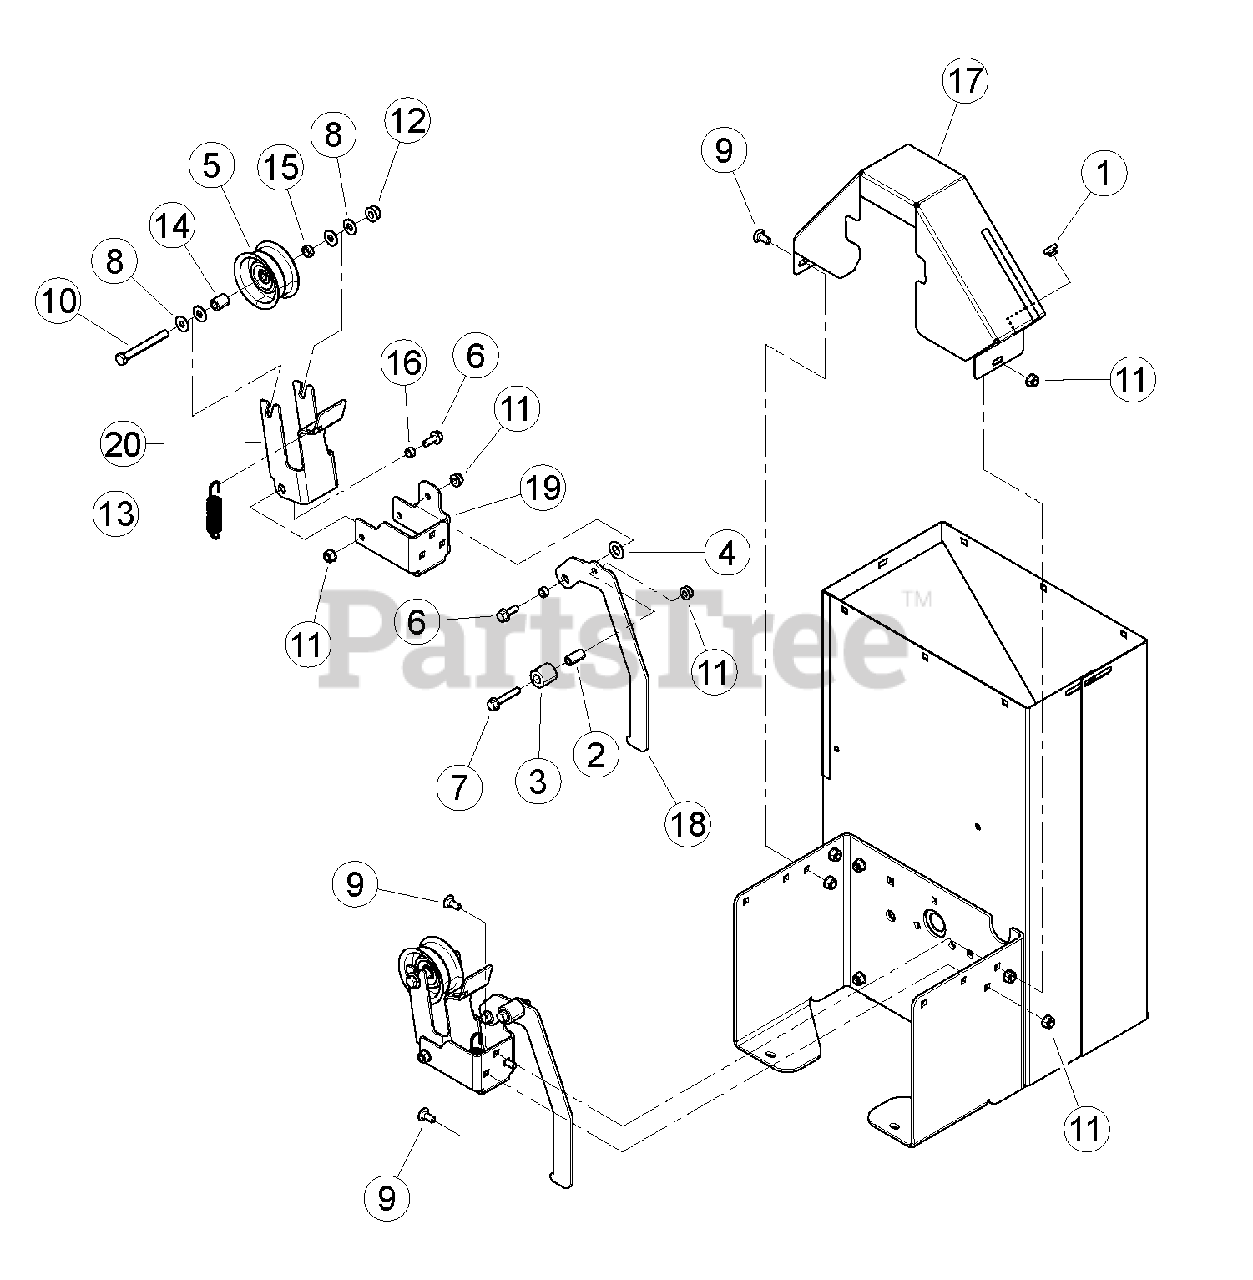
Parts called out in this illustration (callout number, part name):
1	BUMPER, RUBBER
2	SPACER, 0.5 X 1.00
3	ROLLER, 0.5 X 1.00 X 1.00 NYLON
4	WASHER, 1/2 INCH NYLON
5	IDLER, 2.75 X 1.25
6	BOLT, 5/16 X 7/8 FLANGE NC
7	BOLT, 5/16 X 1-3/4 FLANGE NC
8	WASHER, 5/16 FLAT ZP
9	BOLT, 5/16 X 3/4 CRG GR5 NC ZP
10	BOLT, 3/8 X 3-1/4 HEX GR5 ZP
11	NUT, 5/16-18 NYLOCK-FLANGE
12	NUT, 3/8-16 NYLOCK FLANGE
13	SPRING, 3/4" OD EXTENSION
14	SPACER, 3/4" LONG IDLER TUBE
15	SPACER, IDLER PIVOT
16	SPACER, .50 X .25
17	SHIELD, UPPER
18	HANDLE, ENGAGEMENT
19	MOUNT, IDLER BRACKET
20	BRACKET, IDLER 3 IN CHIPPER
